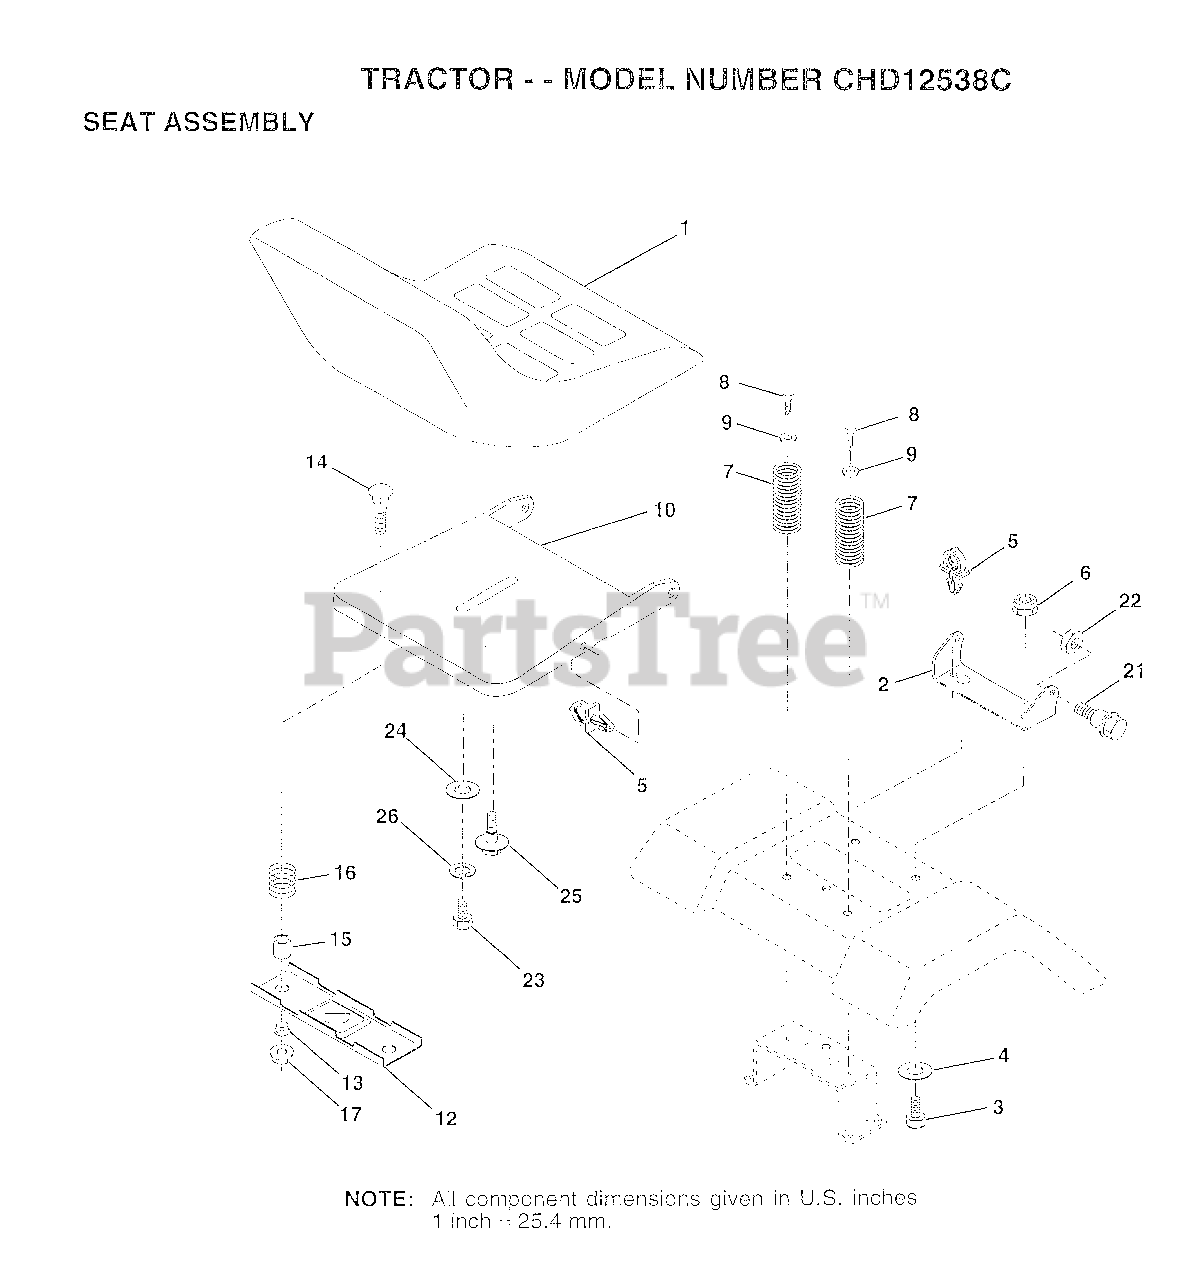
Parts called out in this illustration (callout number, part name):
2	BRACKET PVT SEAT
3	BOLT
4	WASHER PM
5	CLIP.PUSH-IN.HING
6	NUT
7	SPRING COMPRESSIO
8	SCREW GTV
9	WASHER
10	PAN-SEAT
12	BRKT SWITCH
13	BUSHING
14	BOLT-RD HD SQ NK
15	SPLIT SPACER
16	SPRING
21	"BOLT,SHOULDER"
22	NUT
23	BOLT
24	WASHER
25	"BOLT,SHOULDER"
26	LOCKWASHER
